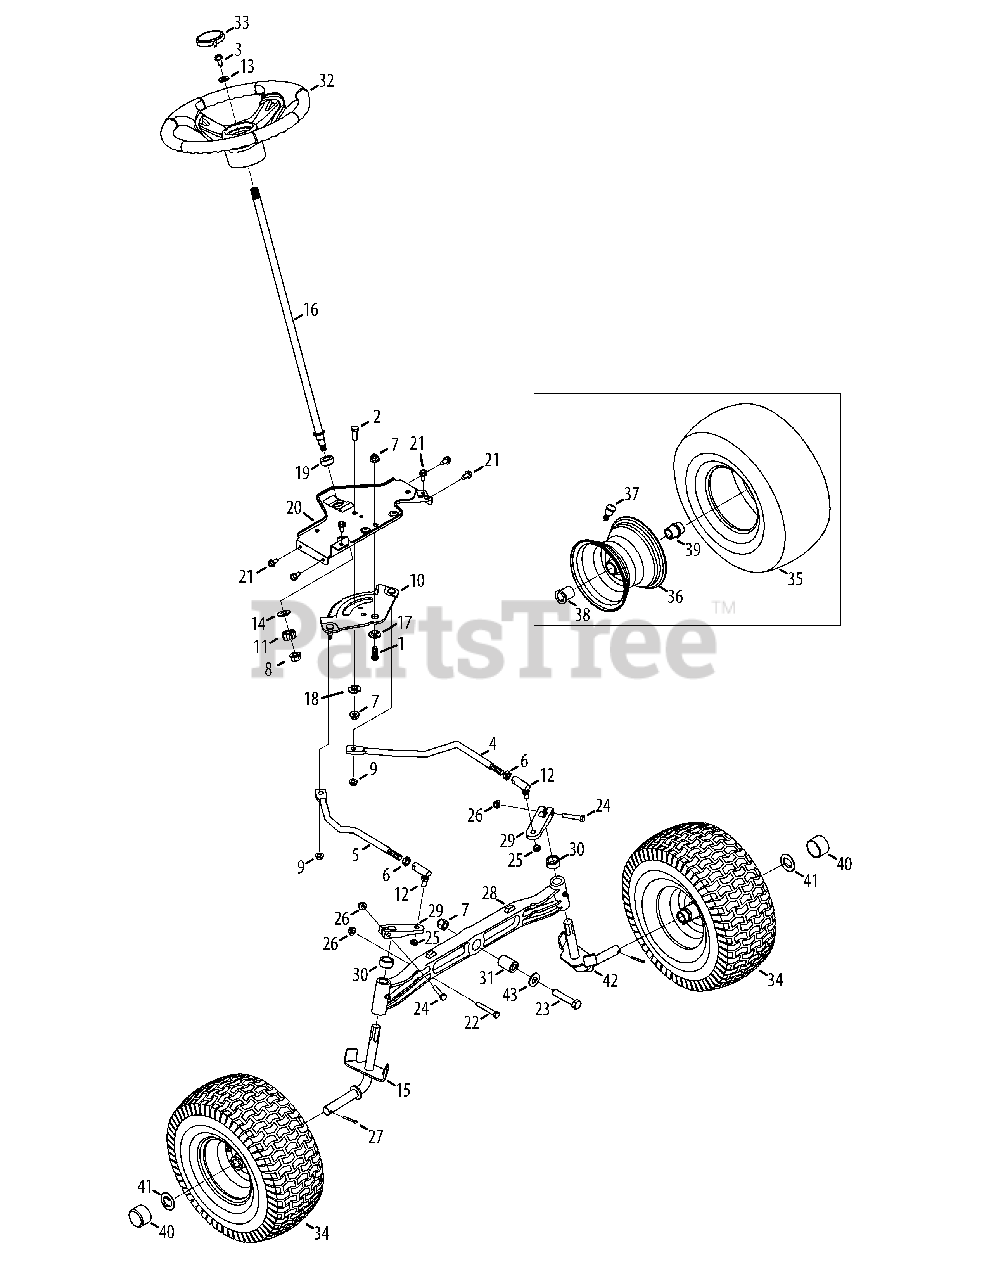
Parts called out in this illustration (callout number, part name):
1	Hex Screw, 3/8-16, 1.00, Gr5, Spec
2	Hex Screw, 3/8-16, 1.00, Gr5, Std
3	Hex Screw, 5/16-18, 1.00, Gr5, Lock
4	Link, Drag LH
5	Link, Drag RH
6	Nut, Jam, 7/16-20, Gr2
7	Nut, Flange Lock, 3/8-16, Grf,
8	Nut, Flange Lock, 7/16-20, Grb, Lock
9	Nut, Flange Lock, 5/16-18, Gr5, Sd Lk
10	Gear, Steering, 11/90 Ratio
11	Gear, Pinion, Steering
12	Ball Joint, 7/16-20, Lock
13	Washer, Flat, .406 x .875 x .105
14	Washer, Flat, .51 x 1.12 x .06
15	Axle Ass’y, RH .750 Dia
16	Shaft, Steering, .625 OD x 24.25
17	Spacer, Shoulder, .385x 1.25 x .3025
18	Spacer, .38 x 1.375, Special, 46" Only
19	Bearing, Flange, Hex 5/8 Pm
20	Bracket, Support, Steering
21	Screw, Self-tapping, 5/16-18, .750,
22	Hex Screw, 5/16-18, 2.25, Gr5, Std
23	Hex Screw, 3/8-16, 2.50, Gr5, Std
24	Hex Screw, 5/16-18, 1.75, Gr5, Std
25	Nut, Hex Lock, 3/8-24, Grb
26	Nut, Flange Lock, 5/16-18, Grf
27	Pin, Cotter, 5/32, 1.25
28	Axle, Pivot Bar, Cast
29	Steering, Block
30	Spacer, .71 ID x .125 OD x .56
31	Spacer, .385 x 1.00 x 1.5075
32	Steering Wheel, Standard Grip
33	Cap, Sprig, Small
34	Wheel Assembly
35	Tire, 15 x 6 x 6
36	Rim Assembly, w/Bearing
37	Tubeless Air Valve
38	Flange Bearing, .760 x 1.00 x 1.20
39	Flange Bearing, .760 ID
40	Cap, Bumper
41	Washer, Flat, .350 x 1.559 x .062
42	Axle Ass’y, LH .750 Dia
43	Washer, Flat, .406 x .875 x .059
